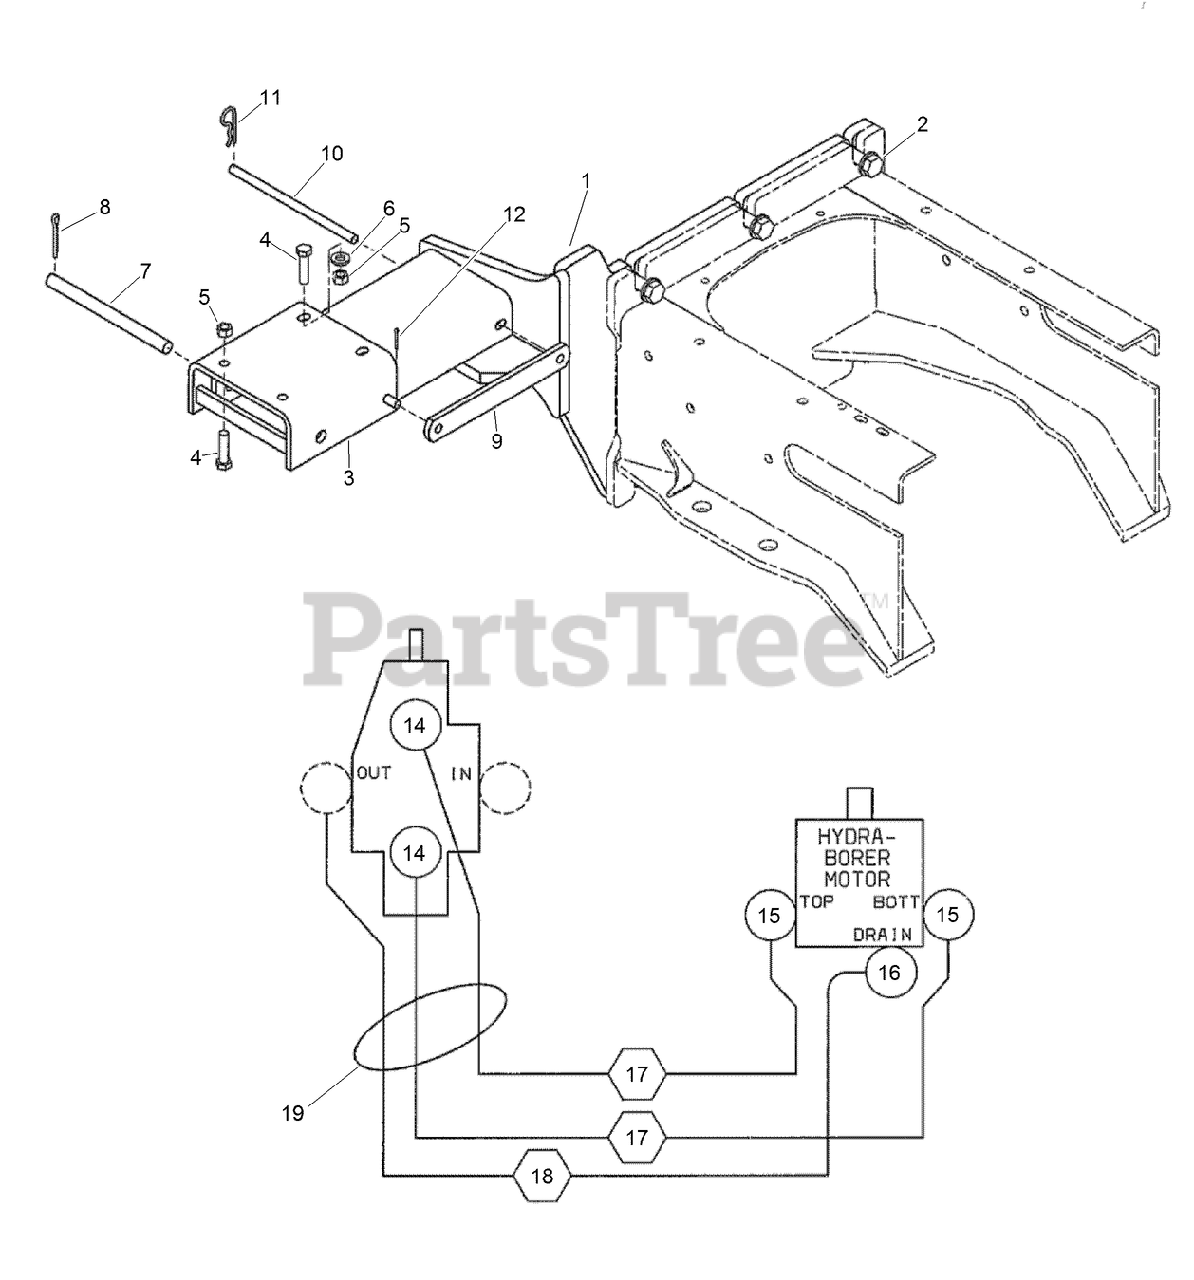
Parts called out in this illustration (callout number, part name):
1	WELDMENT-Frame, Mounting
2	SCREW-HH
3	WELDMENT-Hydra-Borer Mount
5	NUT-HEX
7	PIN-Pivot
8	PIN-Cotter, 0.25 x 1.50 in ZN
9	LINK-Hydra-Borer Support
10	PIN-Pivot
11	PIN-Hair
12	PIN-COTTER
14	CONNECTOR-Str Thd 5/8, 37FL-ORB 5/8
15	ELBOW-90 Adj 37FL 5/8 Tube
16	ELBOW-90 Deg
17	HOSE-Hydraulic
18	ASM-Hose, Tilt
19	STRAP-TIE
